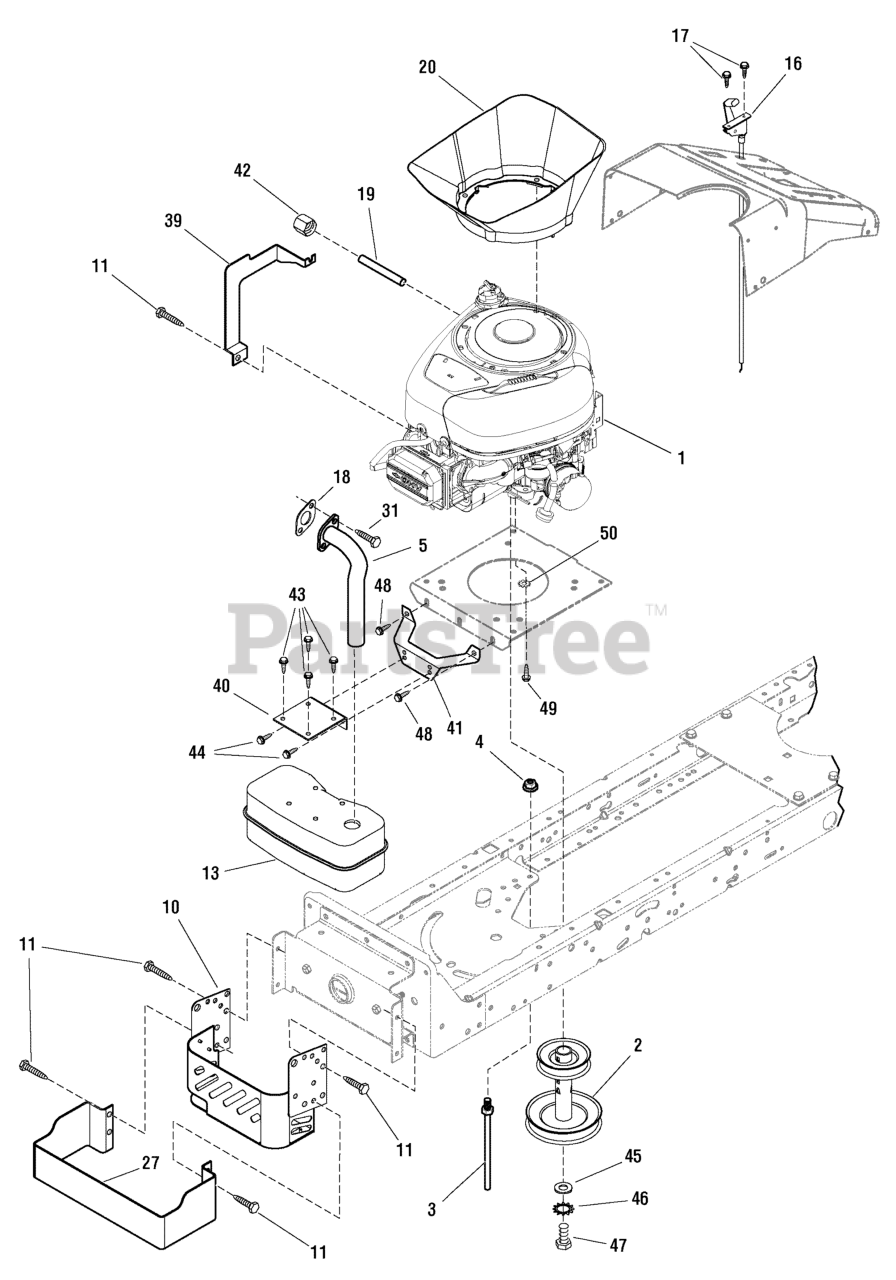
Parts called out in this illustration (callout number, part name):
1	ENGINE, 15.5HP Briggs & Stratton*
2	STACK PULLEY ASSEMBLY
5	EXHAUST TUBE, Single
10	HEAT SHIELD
11	SCREW, Hex Head 5/16-18 x 5/8
13	MUFFLER, Single
16	THROTTLE CONTROL
17	SCREW, Self Tap #8 x 3/8
18	GASKET, Exhaust
19	NIPPLE, Pipe, 3/8 x 3 in
20	PLENUM, Murray
27	GUARD, Heat Shield, Front
31	SCREW, 5/16-18 x 3/4
39	GUARD, Exhaust Pipe
40	BRACKET, Muffler
41	BRACKET, Muffler Mounting
42	CAP, Pipe 3/8
43	SCREW, 1/4-14 x 3/8
44	SCREW, Hex 1/4 x 1/2
45	WASHER, .470- 1.00.25 FLT
46	WASHER, Star, 1/2
47	BOLT, Hex, 7/16-20 x 1-1/2
48	CAPSCREW, 5/16-18 x 3/4
49	BOLT, 3/8-16 x 1-1/4
50	WASHER, Star, 3/8
